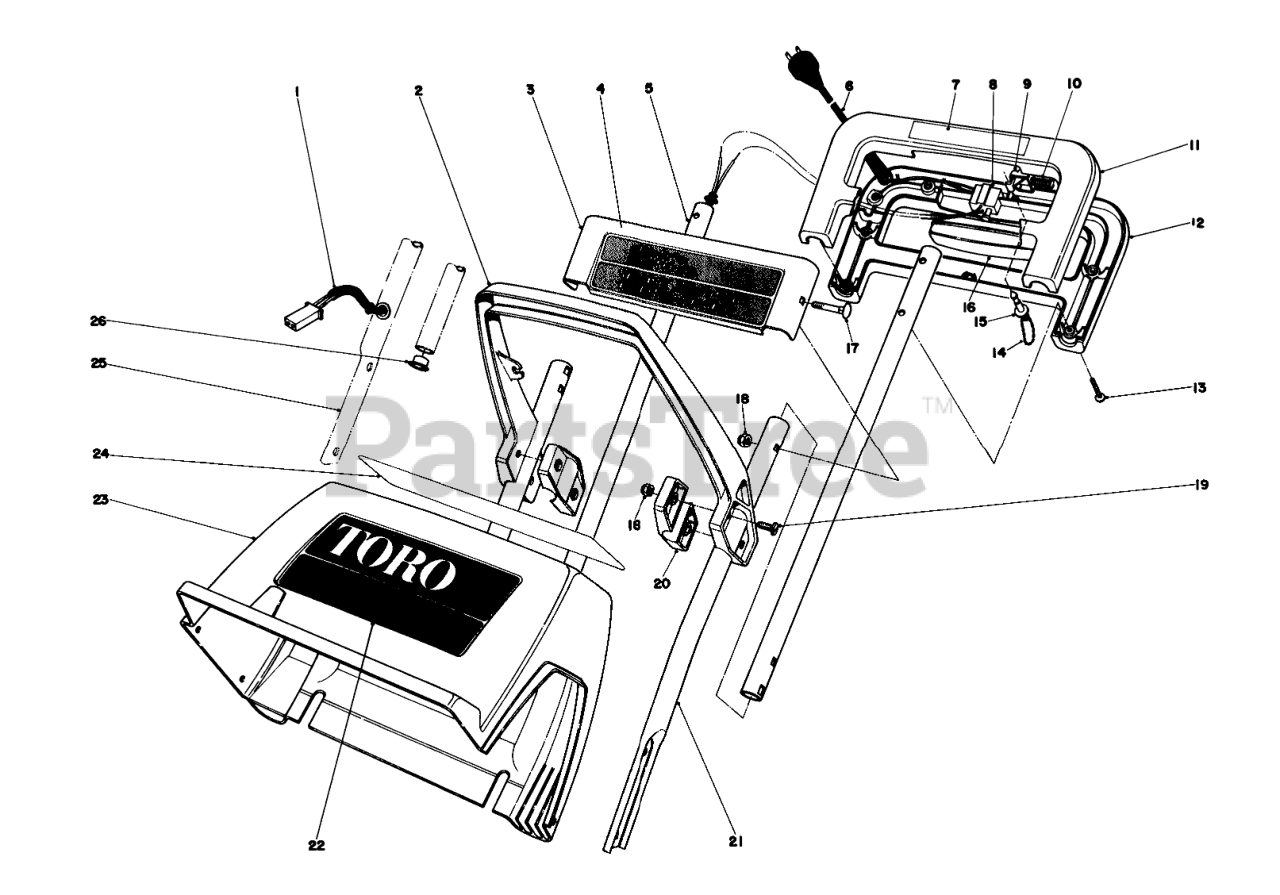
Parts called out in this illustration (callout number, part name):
1	Wire Harness
2	Middle Handle
3	Escutcheon Plate
4	Decal-Electric
5	Upper Tube
6	Cord Supply
7	Decal-Handle
8	SWITCH-STARTER
9	LOCKOUT, 1200
10	COMP SPRING
11	UPPER CONTRL HANDL HID
12	LOWR CONTRL HANDL HID
13	Screw
14	Key Chain
15	Key
16	SWITCH BAR, 1200 PC
17	Bolt-Carriage
18	NUT-LOCK, NI
20	Clamp-Middle Handle
21	Handle-Lower L.H.
22	Decal-Toro S-120
23	Shroud S-120
24	Decal-C.S.A.
25	Handle Lower R.H.
26	Snap Bushing
